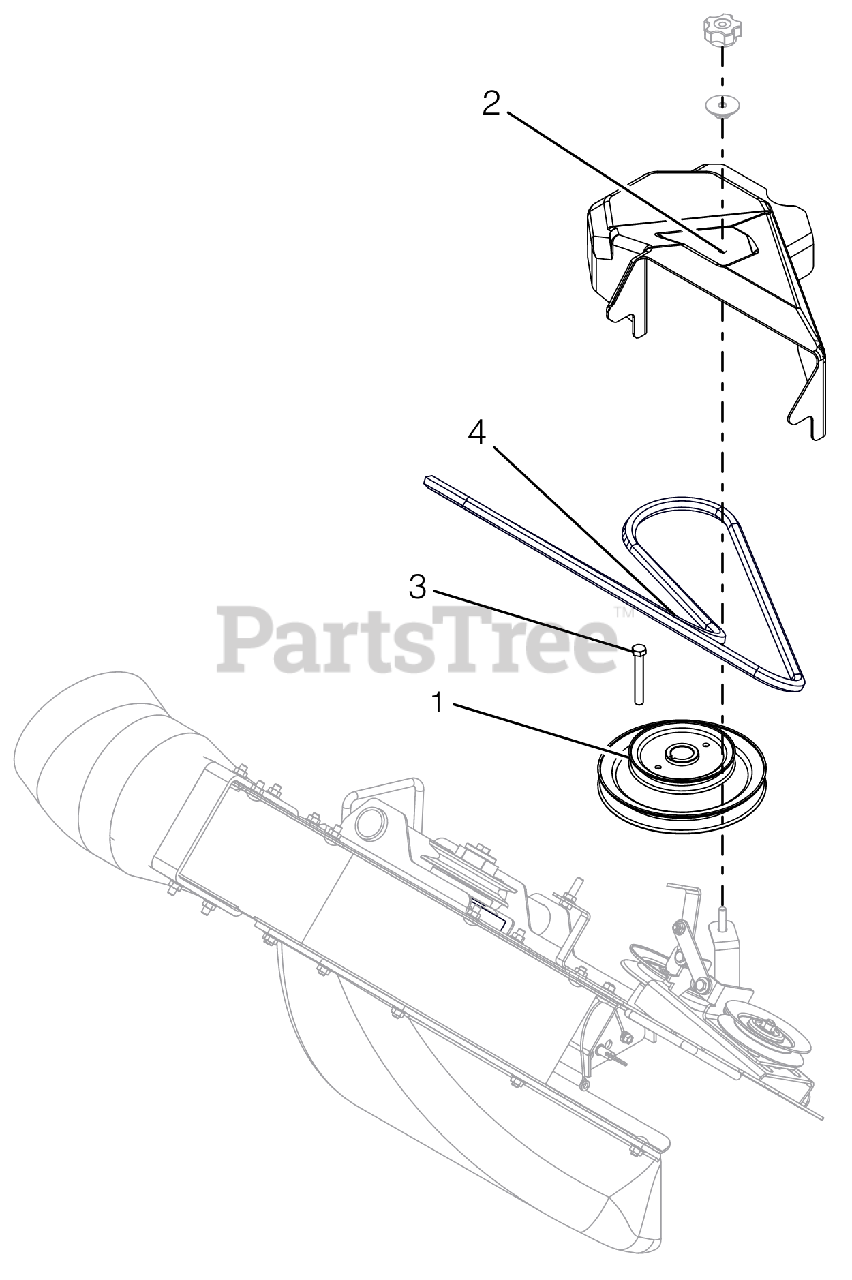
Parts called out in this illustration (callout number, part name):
1	PULLEY, DOUBLE-1"IDX7.50"&4.75
2	COVER, BELT 60 BLOWER
3	BLT-HEX .38-16X2.75 GR8 YWZC
4	HEX BELT, AA-WRAPPED
